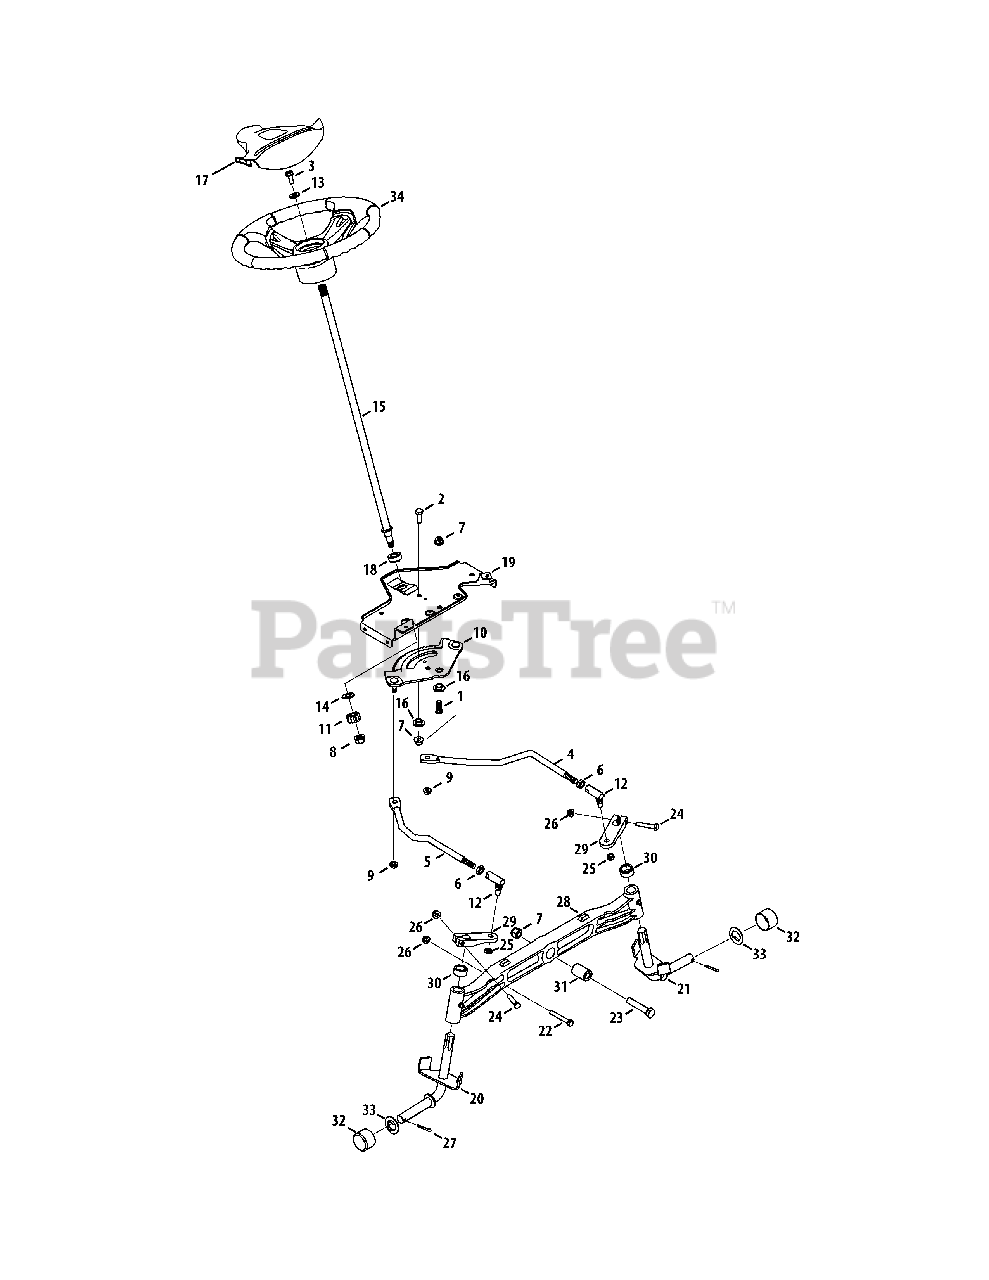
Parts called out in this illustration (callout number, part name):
1	Hex Screw, 3/8-16, 1.00, Gr5, Spec
2	Hex Screw, 3/8-16, 1.00, Gr5, Std
3	Hex Screw, 5/16-18, .875, Gr5, Lock
4	Link, Drag LH
5	Link, Drag RH
6	Nut, Jam, 7/16-20, Gr2
7	Nut, Flange Lock, 3/8-16, Grf,
8	Nut, Flange Lock, 7/16-20, Grb, Lock
9	Nut, Flange Lock, 5/16-18, Gr5, Sd Lk
10	Gear, Steering, 11/90 Ratio
11	Gear, Pinion, Steering
12	Ball Joint, 7/16-20, Lock
13	Washer, Flat, .406 x .875 x .105
14	Washer, Flat, .51 x 1.12 x .06
15	Shaft, Steering, .625 OD x 25, Cub
16	Spacer, Shoulder, .385x 1.25 x .3025
17	Cover, Steering Wheel, Cub Cadet
18	Bearing, Flange, Hex 5/8 Pm
19	Bracket, Support, Steering
20	Axle Ass’y, RH .750 Dia.
21	Axle Ass’y, LH .750 Dia.
22	Hex Screw, 5/16-18, 2.25, Gr5, Std
23	Hex Screw, 3/8-16, 2.50, Gr5, Std
24	Hex Screw, 5/16-18, 1.75, Gr5, Std
25	Nut, Hex Lock, 3/8-24, Grb
26	Nut, Flange Lock, 5/16-18, Grf
27	Pin, Cotter, 5/32, 1.25
28	Axle, Pivot Bar, Cast
29	Steering, Block
30	Spacer, .71 ID x .125 OD x .56
31	Spacer, .385 x 1.00 x 1.5075
32	Cap, Bumper
33	Washer, Flat, .350 x 1.559 x .062
34	Wheel, Steering, 3 Spoke, Softgrip
